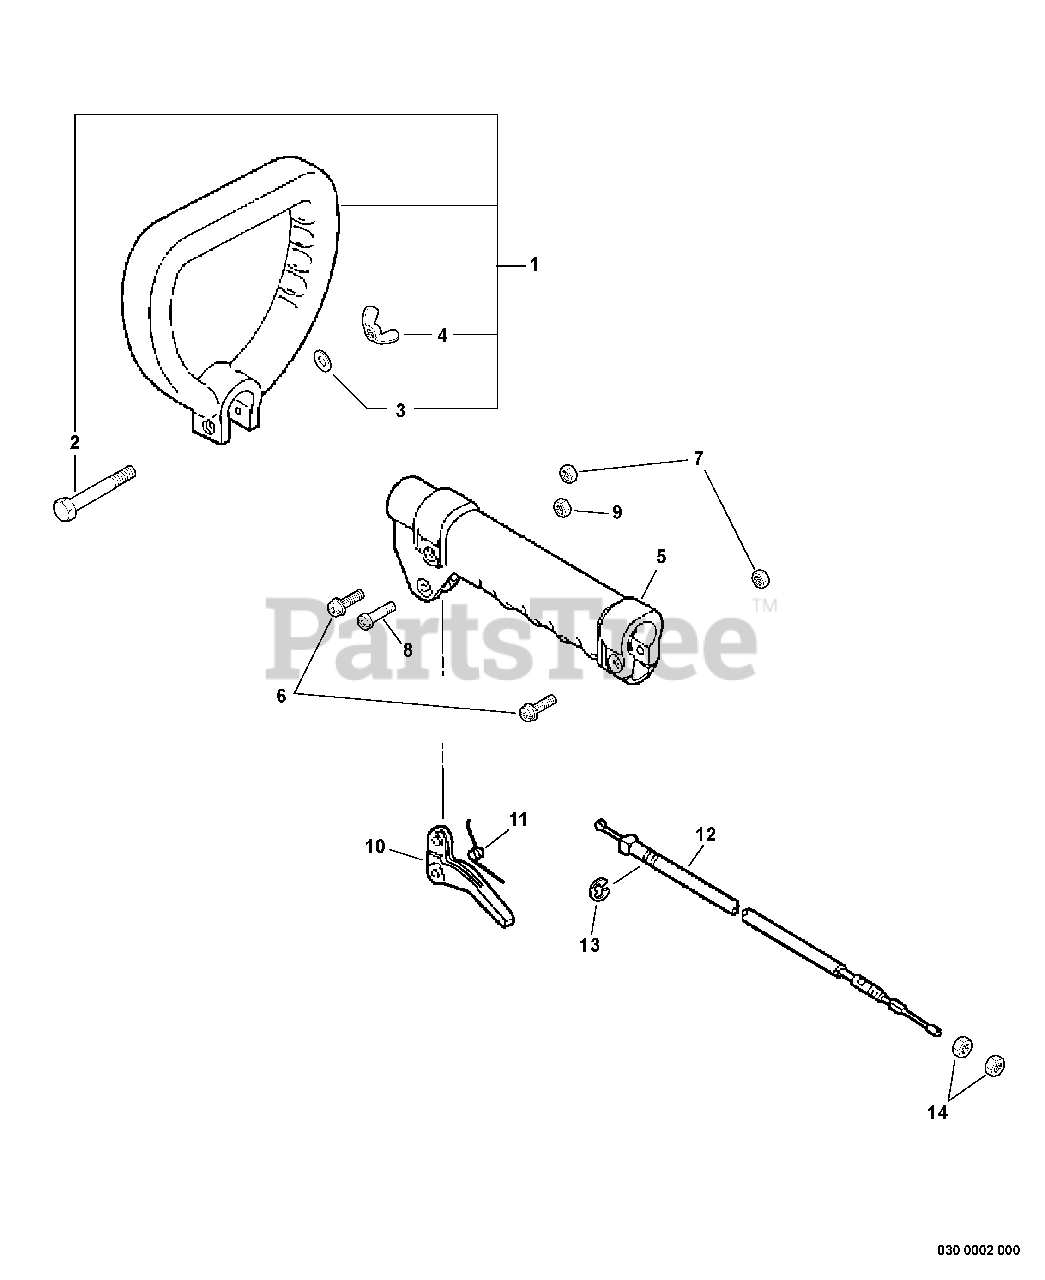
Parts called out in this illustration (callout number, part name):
1	HANDLE ASSY - FRONT
2	BOLT - 1/4-20 X 1-1/2"
3	WASHER - 1/4"
4	WINGNUT - 1/4-20
5	GRIP, HANDLE
6	SCREW - 5X25
8	SCREW - 5X30
9	LOCKNUT - 5
10	TRIGGER, THROTTLE
11	SPRING, TRIGGER
12	CABLE, THROTTLE
13	RING, RETAINING - 5
